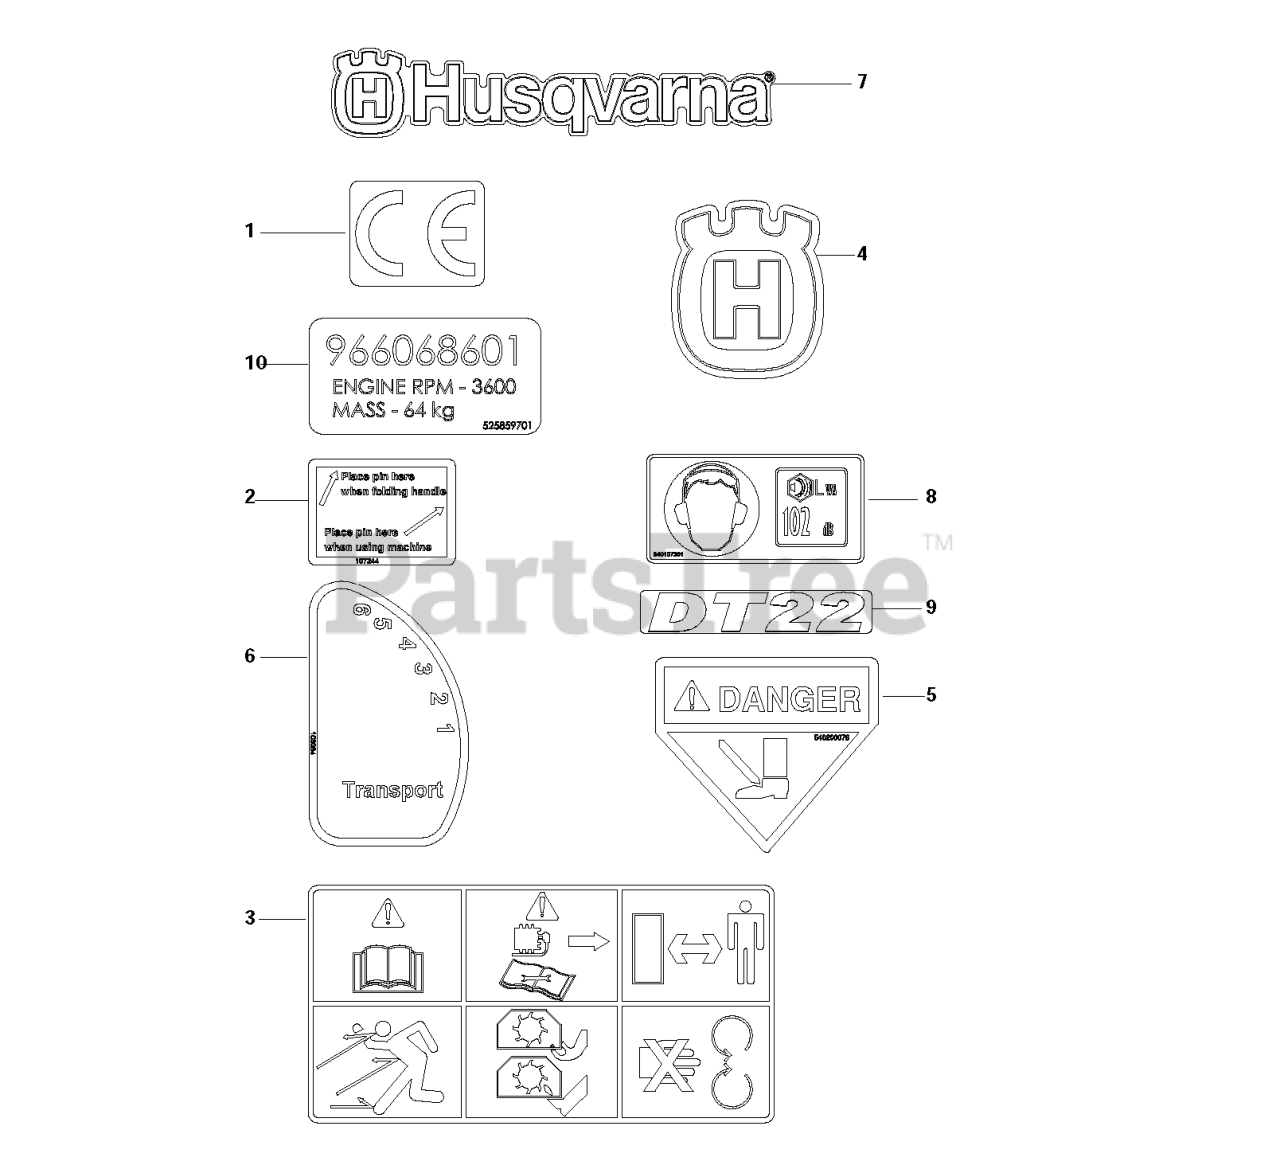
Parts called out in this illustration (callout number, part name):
2	DECAL, HANDLE PIN
3	DECAL, SAFETY GRAPHICS
4	DECAL, CROWN H 70MM
5	DECAL, FOOT DANGER
6	DEPTH DECAL
7	DECAL.HOOD.LOGO.ORANGE.HUSQVAR
8	DECAL, SOUND POWER
9	DECAL, DT22
10	DECAL, CD 966068601
